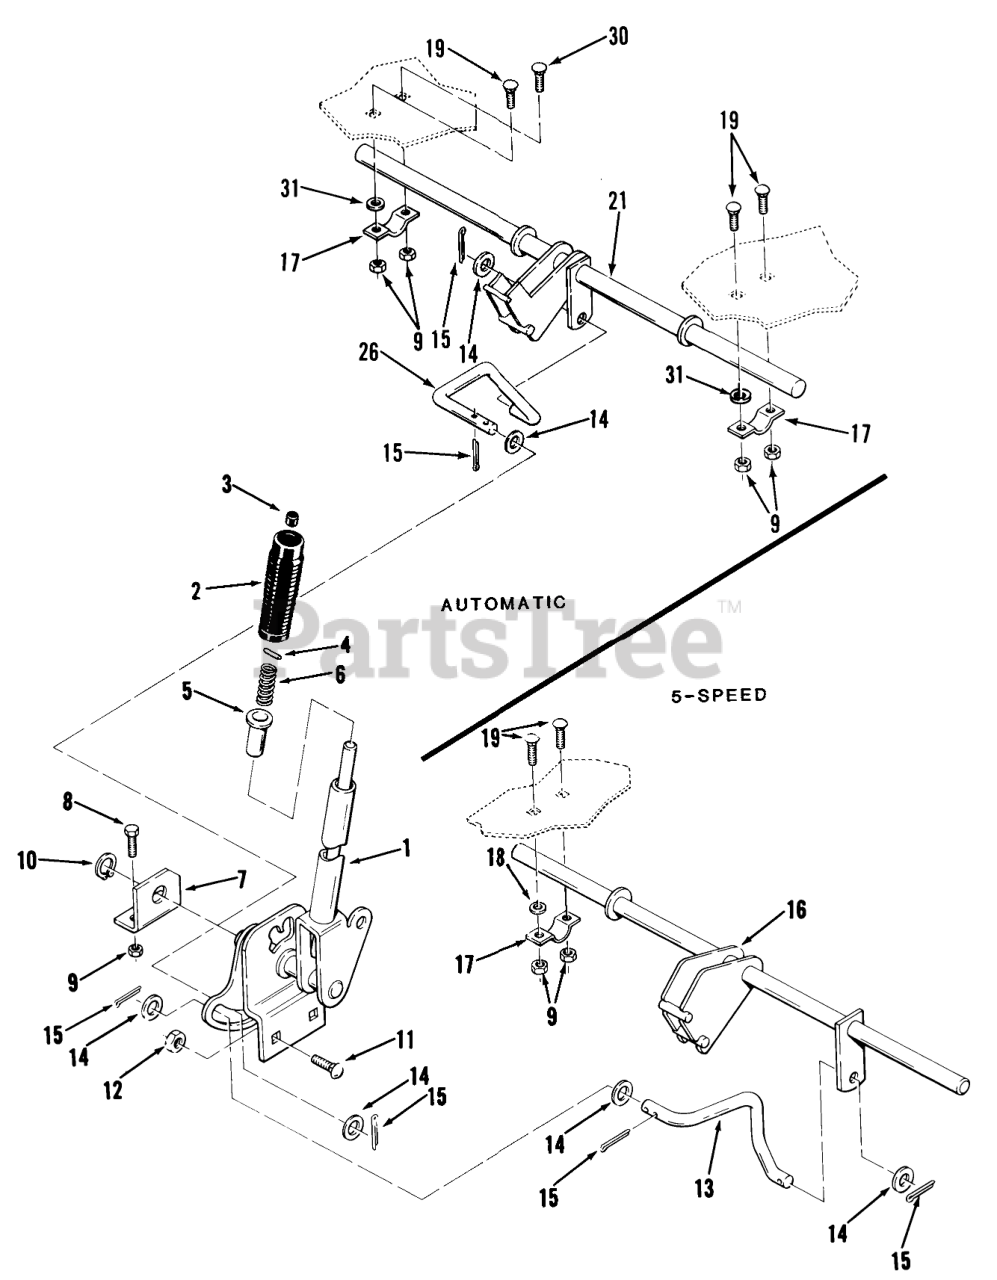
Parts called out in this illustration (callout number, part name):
1	Lift Lever
2	HANDGRIP
3	CAP-ROD, PLUNGER
4	PIN-SPIROL
5	RETAINER-SPRING
6	SPRING-COMPRESSION
7	BRACKET-INNER R
8	Bolt
9	Nut
10	Snap Ring
11	Bolt-Carriage
12	Nut
13	ROD LIFT
14	Washer
16	ASM-REAR LIFT R
17	CLAMP
18	Washer
19	CARRIAGE BOLT -4
21	ASSY REAR LIFT R
26	ROD LIFT R
30	Bolt-Carriage
31	Washer
